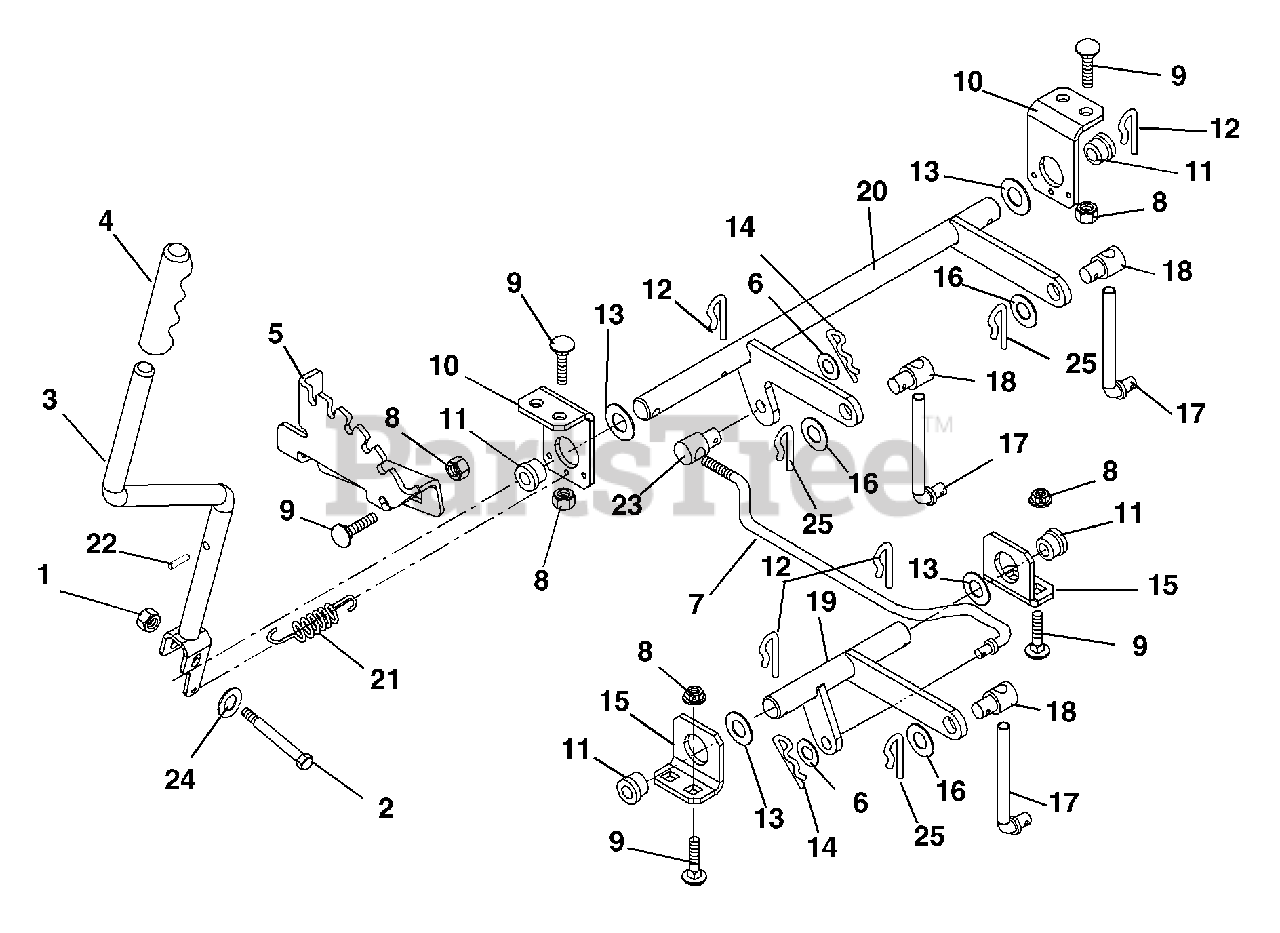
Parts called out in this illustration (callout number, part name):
1	NUT-LK-TOP-FLG .31-18 BLKZC
2	BOLT,SHLDR .38X1.25 .31-18 PLN
3	WLDMT-LIFT HANDLE
5	DETENT PLATE
6	WSHR-FL-STL .505X1.00X.062YWZC
7	ROD, DECK LIFT
8	NUT-LK-TOP-FLG .38-16 BLKZC
9	BLT-RDHDSQNK .38-16X.75 G5BZ
10	BRACKET-HANGER
11	BSHG-FLG .750X1.000X.625X1.250
12	PIN, SPRING CLIP
13	@WSHR-FL-STL.563X1.38X.109YWZC
14	PIN, HAIR, EXT - #16 YWZC
15	BRACKET-PIVOT
16	WSHR-FL-STL.511X1.441X.125 YWZ
17	LINK, LIFT
18	TRUNNION-.50
19	WMT, FRONT LIFT
20	WMT, REAR LIFT
21	SPRING, EXTENSION
22	PIN-ROLL .250X1.25
23	PIVOT, ROD
24	WSHR,FLT .438X1.00X.160 ZCC
25	CLIP, SPRING
